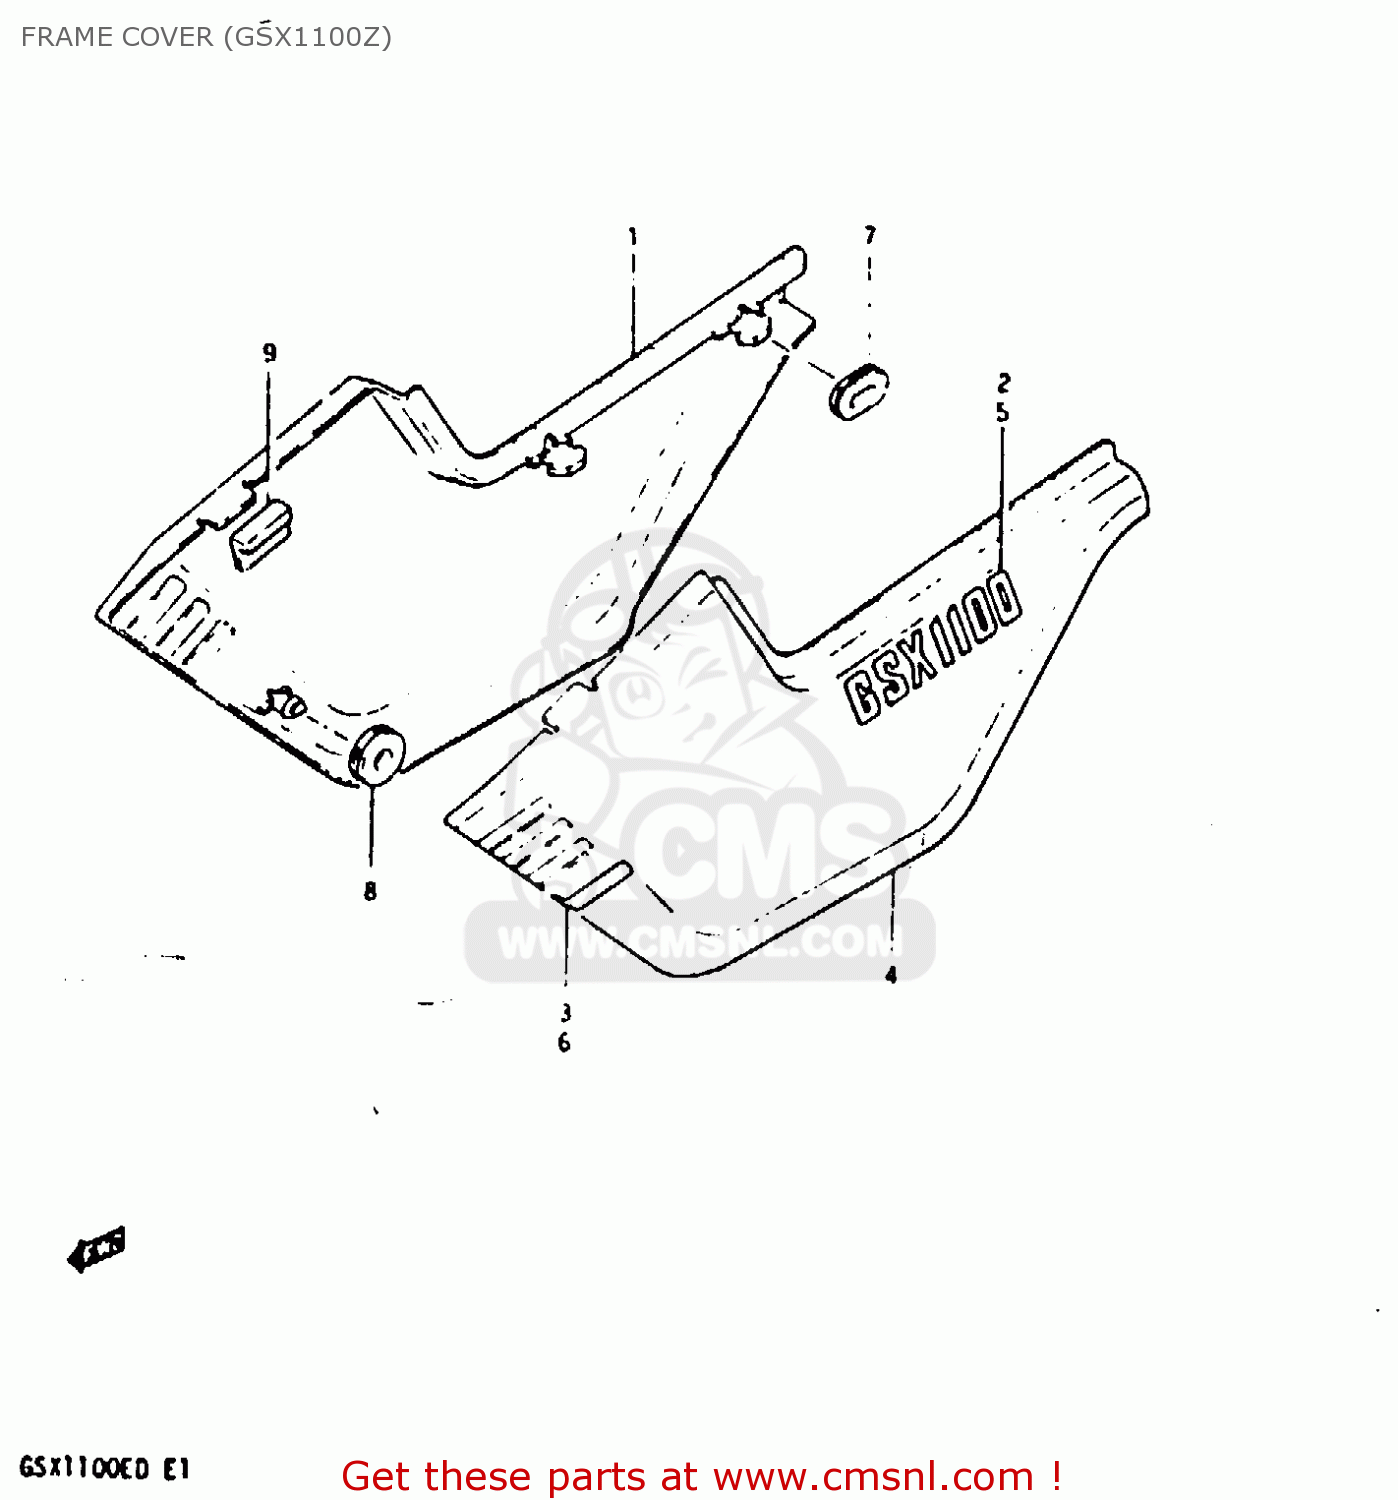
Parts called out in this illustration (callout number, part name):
1	COVER, FRAME RH (GOLD)
2	EMBLEM, LH
3	LABEL, DENT
4	COVER, FRAME LH (GOLD)
5	EMBLEM, LH
6	EMBLEM,FRAME COVER,CENTER
7	CUSHION
8	CUSHION
9	CUSHION,FRAME COVER
